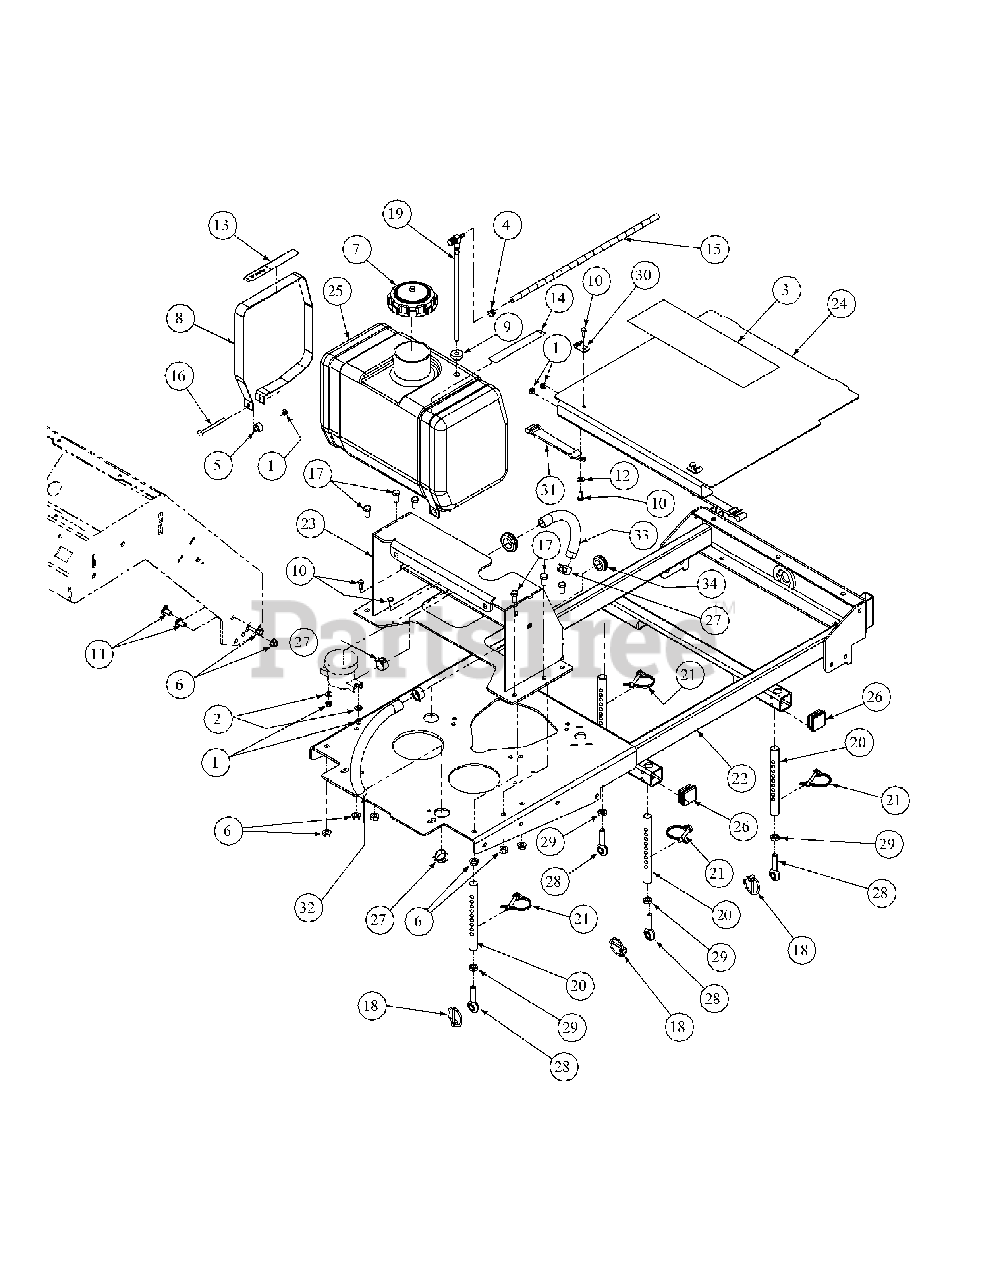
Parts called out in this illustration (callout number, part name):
1	Nut, 1/4-20, Nylon Insert
2	Washer, 1/4 Zinc
4	Clamp
5	Spacer, Drive Wheel
6	Nut, 3/8-16, Hex Flange Lock
8	Fuel Tank Strap
9	Fuel Tank Grommet
10	Hex Cap Screw, 1/4-20 x .620
11	Carriage Bolt, 3/8-16 x .75
12	Washer, 1/4 x .630 x .0515
13	Label, Warning Turn Off Engine
14	Label, Fuel Valve Info
15	Fuel Hose, 18" Long
16	Carriage Bolt, 1/4-20 x 3.00
17	Hex Cap Screw, 3/8-16 x .750
18	Linch Pin, 3/16 Dia.
19	Fitting, Fuel Pickup
20	Rod End, 3/4 Dia.
21	Pin, 1/4" Lock Wire
22	Frame Weldment
23	Handle Mount Weldment
24	Deck Belt Cover, Black
24	Deck Belt Cover, Yellow
25	Fuel Tank
26	Square Cap, 1.50"
27	Hose Clamp, 7/8"
28	Male Rod End
29	Nut, 7/16-20 Hex Jam
30	Hook Retainer Bracket
31	Strap Retainer Assembly
32	Right Hand Tube Tank, 12"
33	Left Hand Tube Tank, 10"
34	Rubber Grommet
